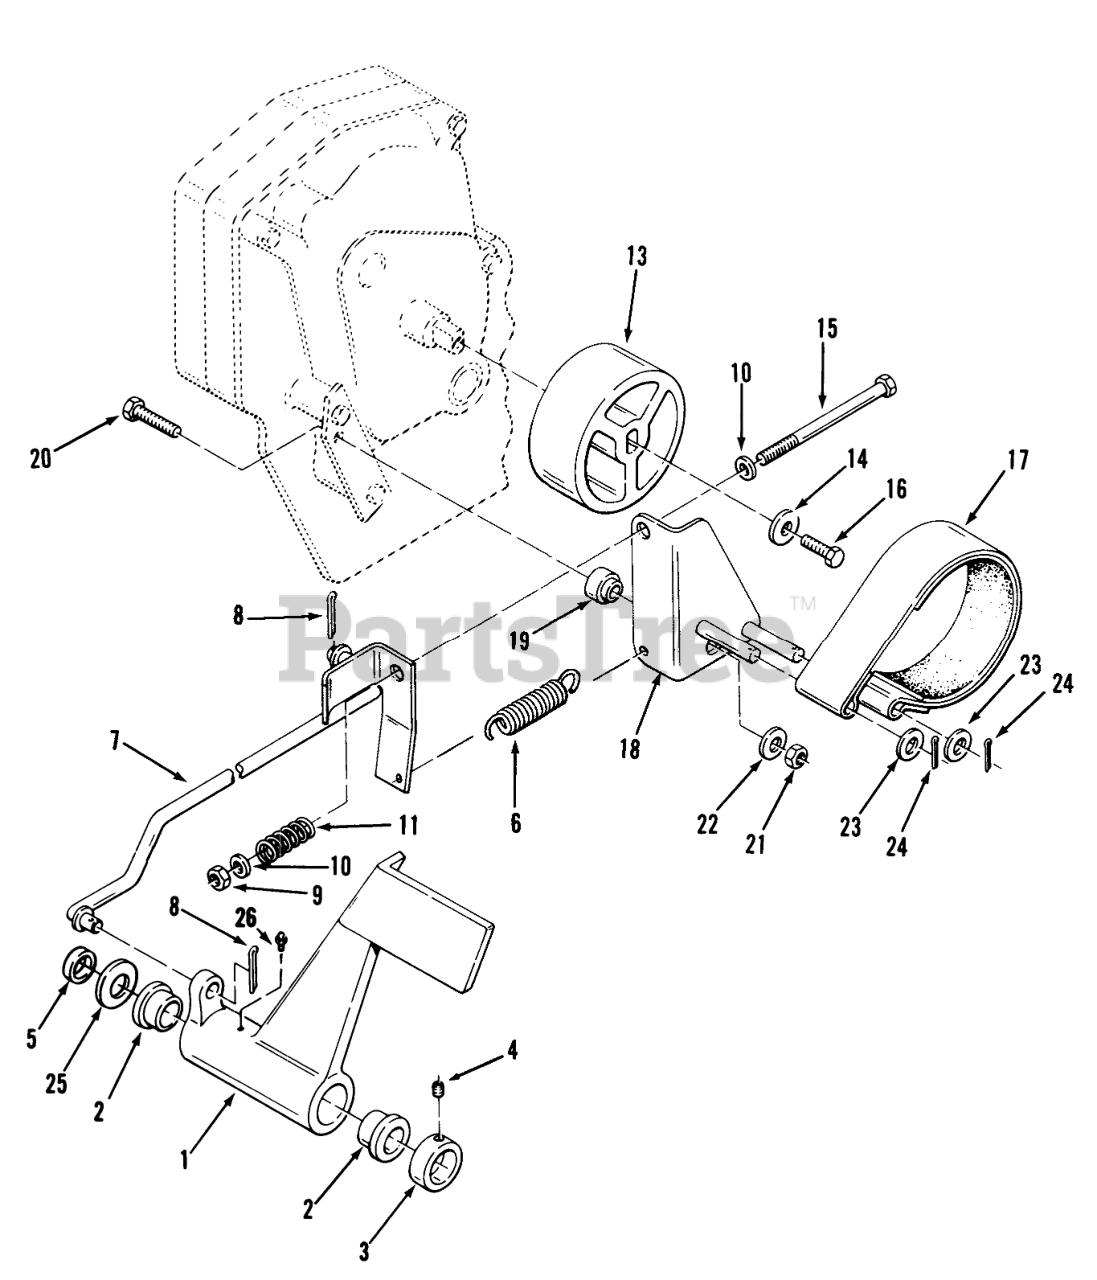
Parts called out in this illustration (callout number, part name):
1	Pedal-Brake
2	BUSHING
3	Collar
4	SCREW-SET
5	SPACER
6	SPRING
7	ASY BRAK RD WAR
9	NUT
10	Washer
11	SPRING-COMPRESSION
13	DRUM-BRAKE
14	WASHER
15	BOLT
16	BOLT
17	ASSY-BRAKE BAND
18	BRACKET-BRAKEB
19	BUSHING-BRAKE PIVOT
20	Bolt
21	NUT
22	Washer
23	Washer
24	Cotter Pin
25	WASHER
26	Zerk
